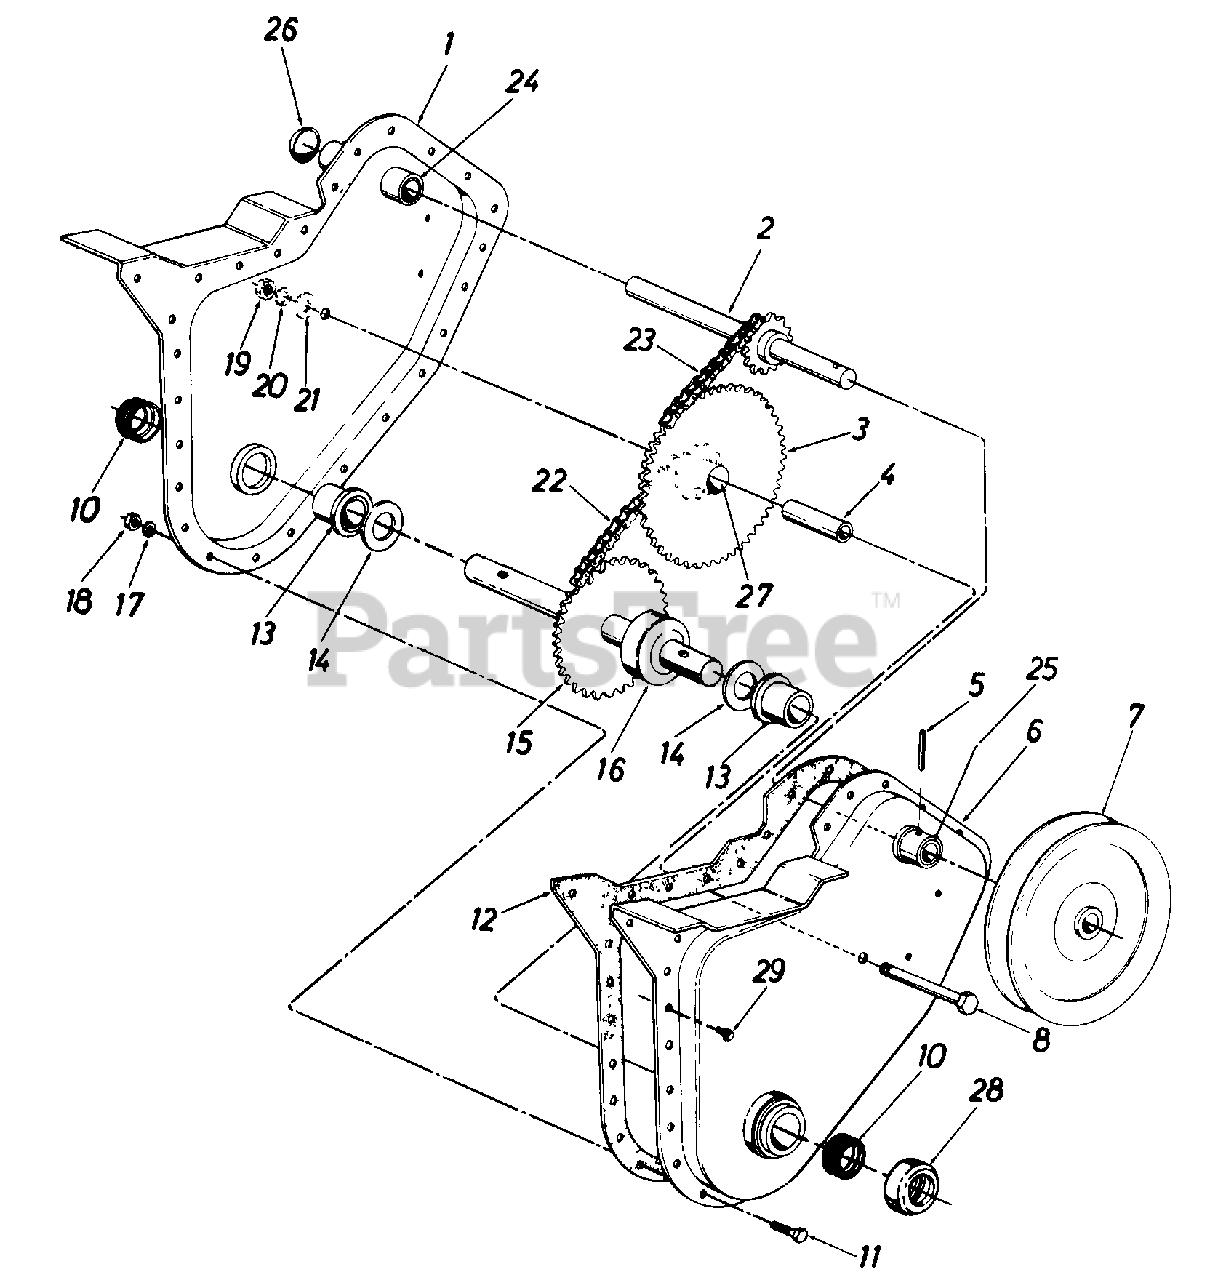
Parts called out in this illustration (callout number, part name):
1	Chain Case Ass'y. - R.H.
2	Input Shaft Ass'y.
3	Hub and Sprocket Ass'y.
4	Bearing Inner Race
5	Spring Pin Spiral 1/4" Dia. x 1.50" Lg.
6	Chain Case Ass'y. - L.H.
7	Pulley - Chain Case 5 1/2 x 1/2
8	Hex Bolt 3/8-24 x 2.50" Lg.
10	Seal
11	Hex Bolt 1/4-28 x .625" Lg.
12	Gasket
13	Flange Brg. .879 I.D.
14	Fl-Wash. .88 I.D. x 1.50 O.D. x .030
15	Tine Shaft Ass'y.
16	Spacer 7/8" I.D. x 2.0" O.D. x .68" Lg.
17	L-Wash. 1/4" Scr.
18	Hex Nut 1/4-28 Thd.
19	Hex Nut 3/8-24 Thd.
20	L-Wash. 3/8" Scr.
21	Bell-Wash. .406 I.D. x 1.130 O.D.
22	Chain #420 - .50" Pitch x 38 Links
23	Chain #35 - .375" Pitch x 50 Links
24	Bearing .62" I.D. x .813 O.D. x 1.31
25	Bearing .62" I.D. x .813 O.D. x 2.06
26	Expansion Plug 13/16" Dia.
28	Dust Cap
29	Hex Wash. Hd. Self-Tap Scr. 1/4-20 x .50" Lg.
